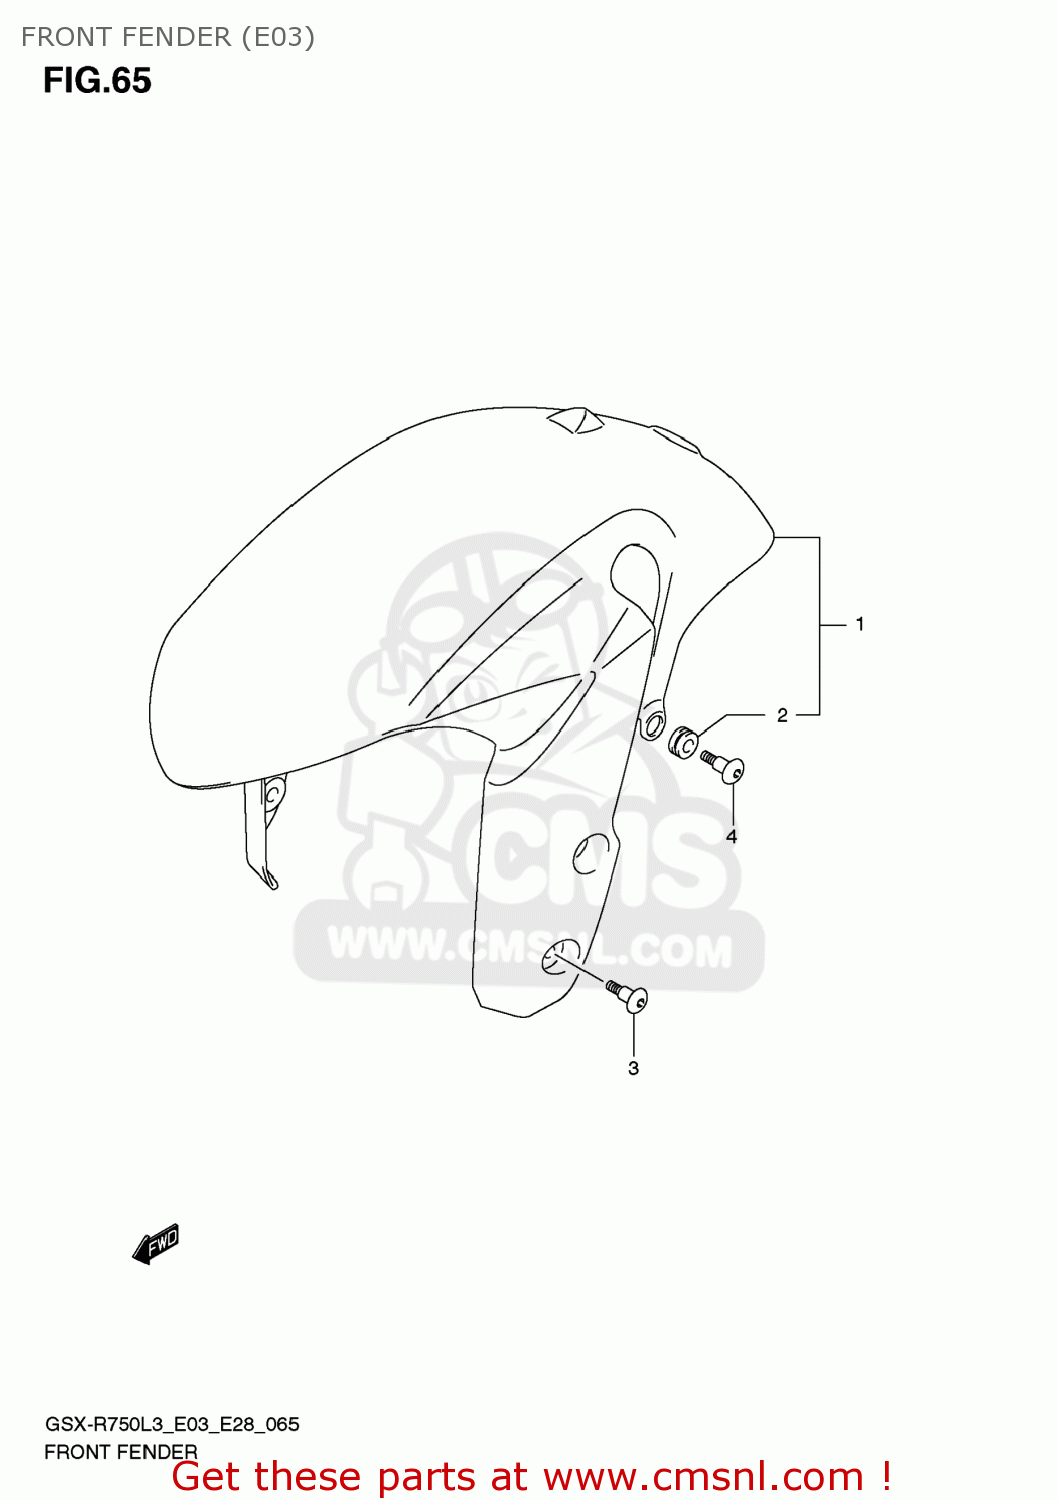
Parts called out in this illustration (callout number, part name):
1	FENDER ASSY,FR(BLACK)
2	CUSHION
3	SCREW(6X16)
4	SCREW(6X16)
